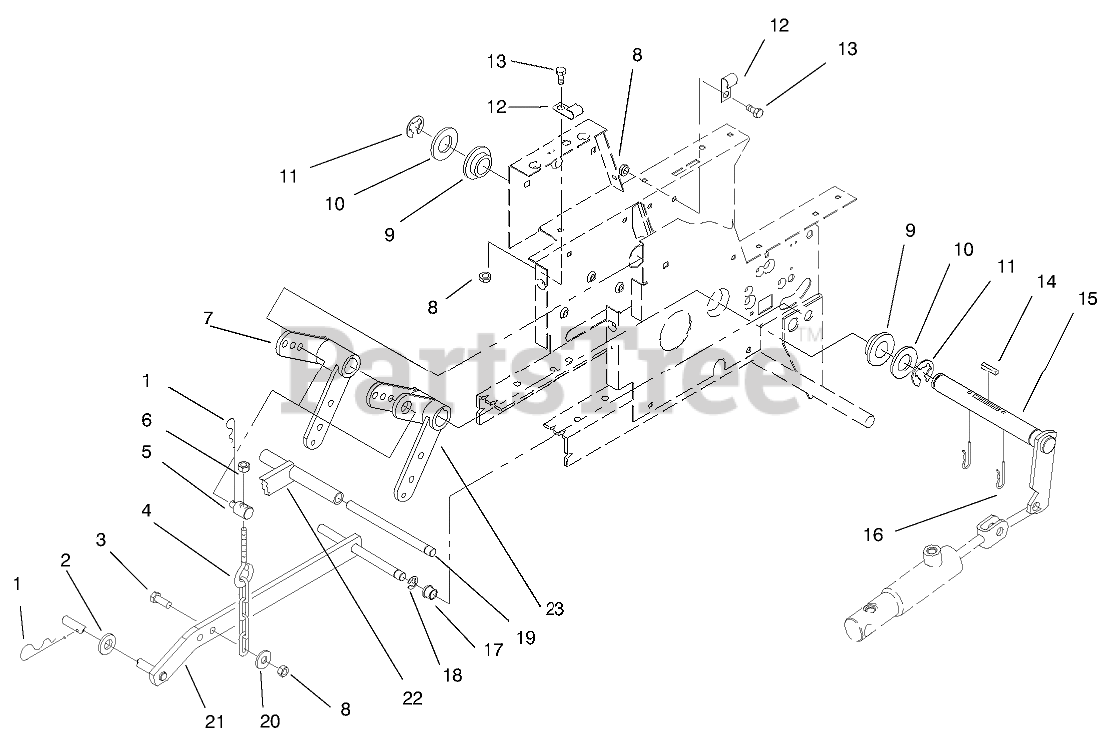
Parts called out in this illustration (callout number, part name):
1	PIN-HAIR
2	WASHER-FLAT
3	SCREW-HH
4	CHAIN-LIFT
5	TRUNNION
6	NUT-LOCK, NI
8	NUT-LOCK, NI
9	BEARING-FLANGE
10	WASHER-FLAT
11	RING-RETAINING
12	CLIP
13	SCREW-HH
14	KEY-SQUARE
15	WLDMT-LIFT ARM
16	PIN-HAIR
17	BUSHING
18	RING-RETAINING, EXTERNAL
19	PIN-PIVOT
20	WASHER-PLAIN
22	LIFT BAR WA (BLACK)
23	WLDMT-LIFT LEVER
32	ADAPTOR - HOSE, 45 DEGREE
